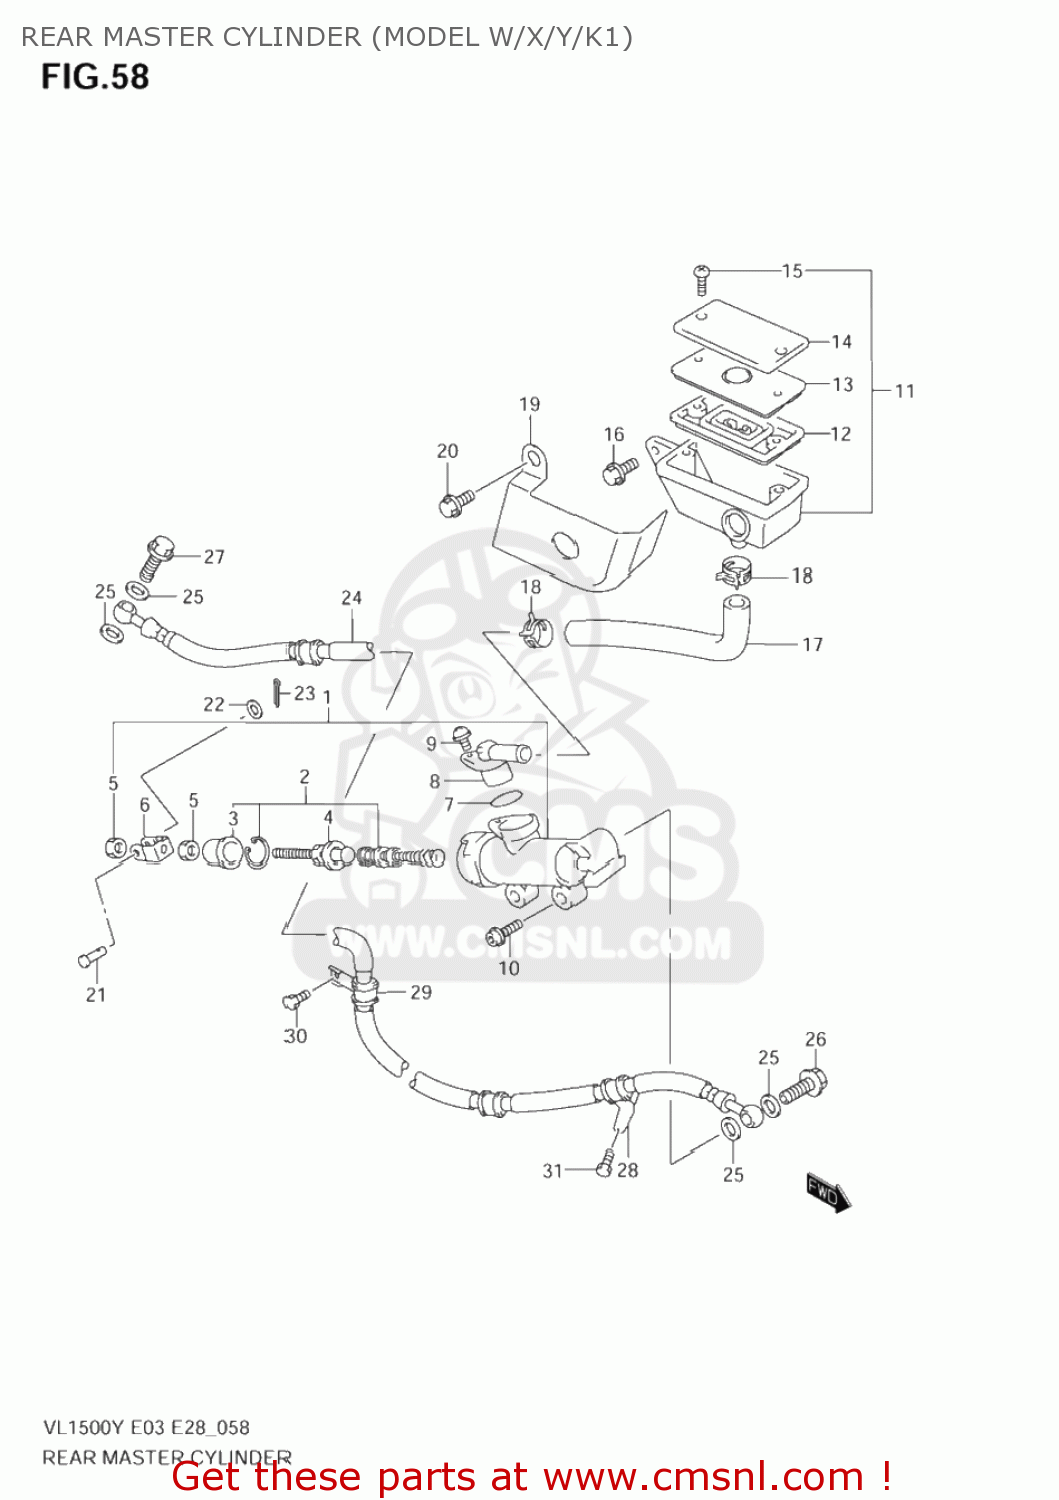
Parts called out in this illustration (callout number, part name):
1	CYLINDER ASSY,RR MASTER
2	PISTON/CUP SET
3	BOOT
4	ROD,PUSH
5	NUT
6	YOKE
7	O RING
8	CONNECTOR
9	SCREW
10	BOLT MAGNETO S
11	TANK ASSY,RR RESERVOIR
12	13
13	PLATE,DIAPHRAGM
14	CAP
15	SCREW
16	BOLT
17	HOSE,RESERVOIR TANK
18	CLIP
19	COVER,RESERVOIR TANK
20	BOLT
21	PIN
22	WASHER
23	PIN
24	HOSE,RR BRAKE
25	WASHER(10X15X1.5)
26	BOLT UNION
27	BOLT UNION
28	CLAMP,RR BRAKE HOSE NO.1
29	CLAMP,FRONT BRAKE NO.2
30	BOLT
31	BOLT
